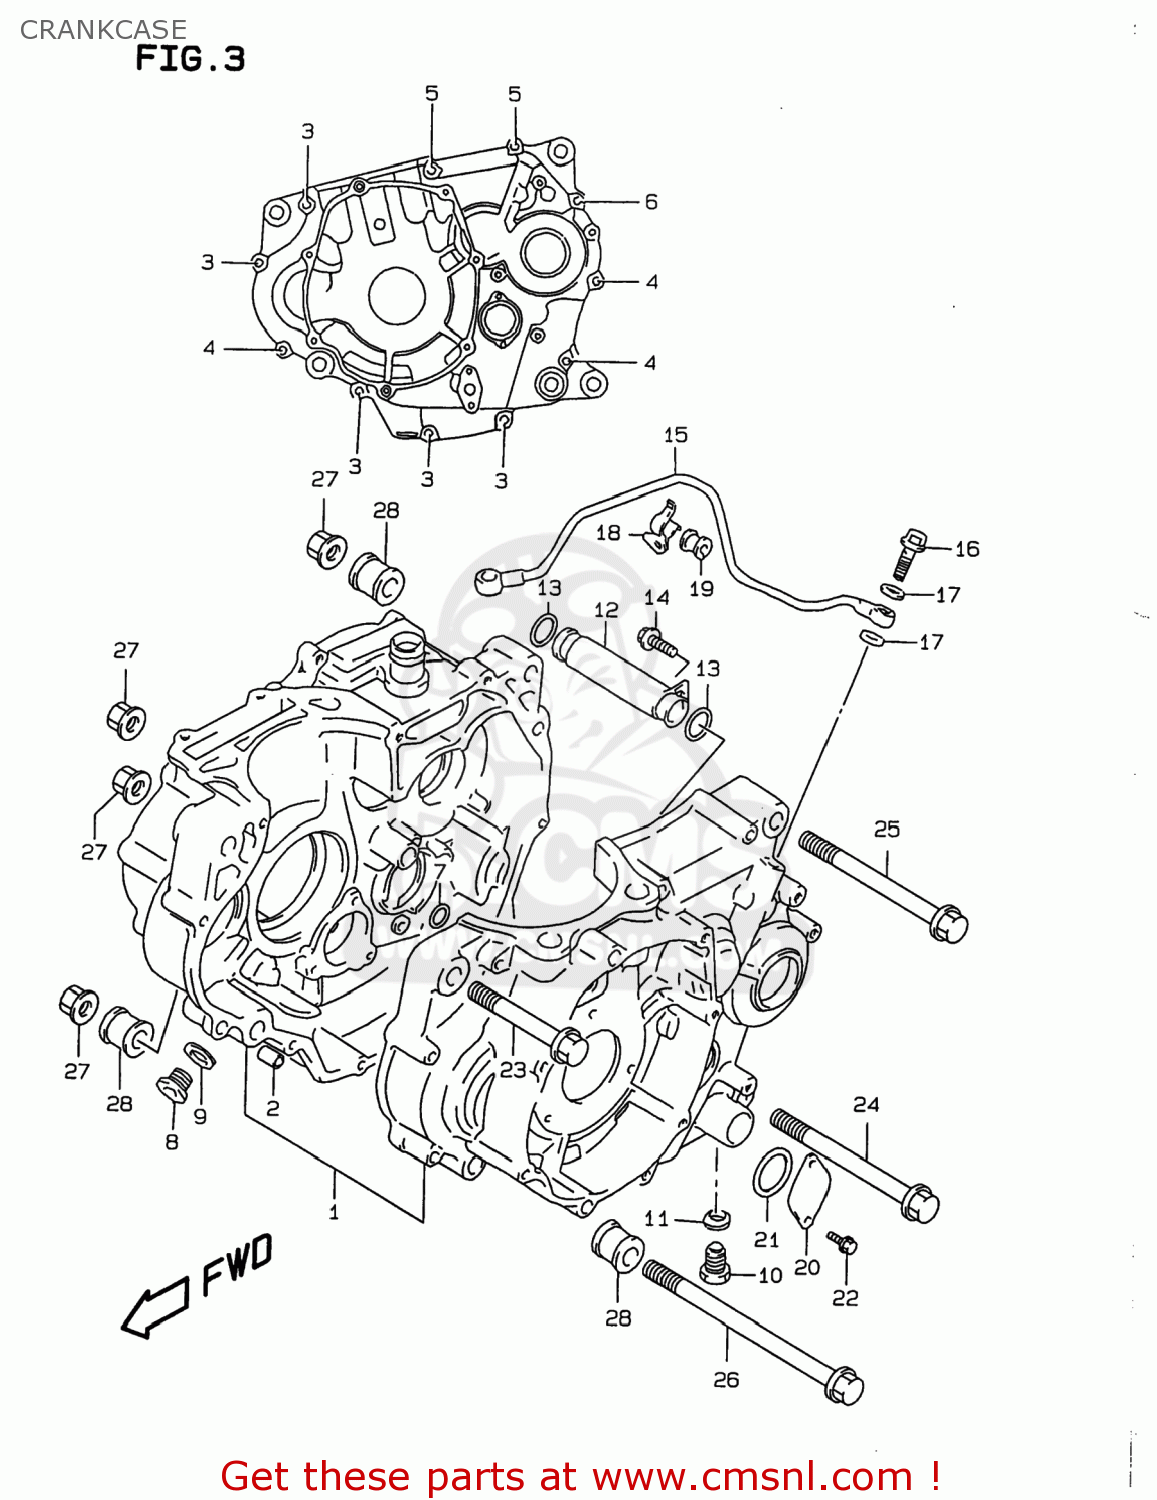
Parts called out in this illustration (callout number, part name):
1	CRANKCASE SET
2	PIN
3	BOLT
4	BOLT
5	BOLT
6	BOLT
7	O RING(D:1.9,ID:12.6)
8	PLUG,14X12
9	GASKET(13.8X18.8X4.8) (NAS)
10	BOLT
11	GASKET(12.1X16.2X3.7) (NAS)
12	PIPE,T/M OIL INNER
13	O RING(D:2.4,ID:15.8)
14	BOLT
15	PIPE,T/M OIL OUTER
16	BOLT UNION
17	GASKET 8.2X14X1 (NAS)
18	CLAMP,OIL PIPE
19	CUSHION
20	CAP,NEUTRAL SWITCH HOLE
21	O RING(D:2.4,ID:26.2)
22	BOLT
23	BOLT 10X85
24	BOLT(10X101.5)
25	BOLT(10X115)
26	BOLT(10X143)
27	NUT
28	SPACER,ENGINE MOUNTING
